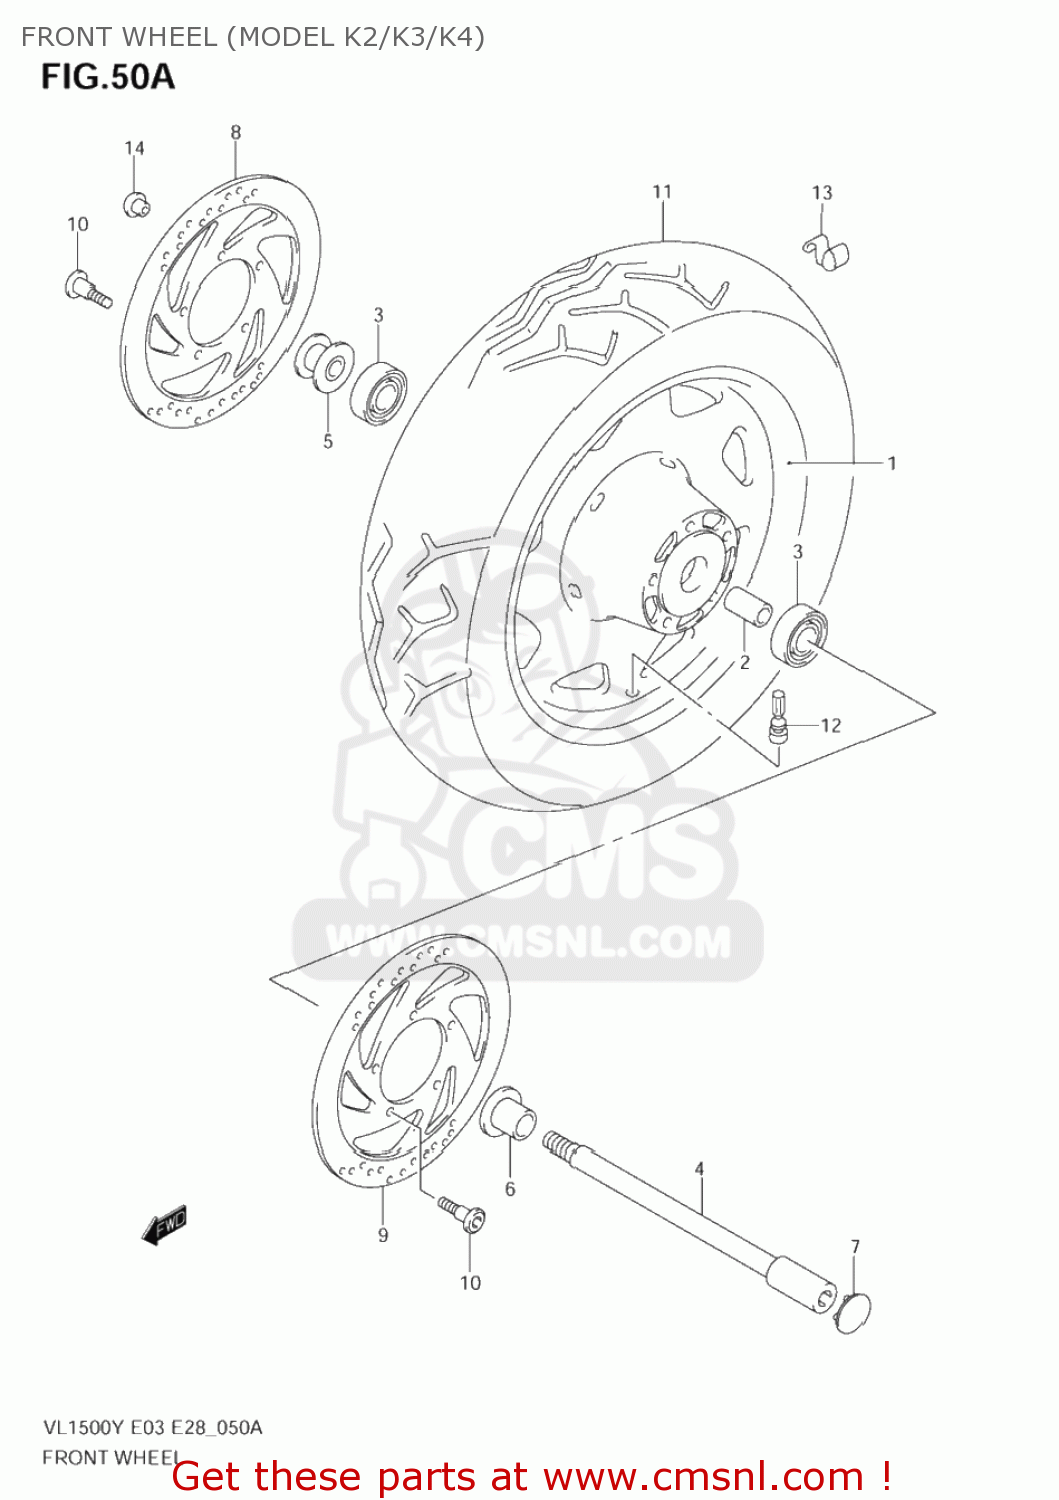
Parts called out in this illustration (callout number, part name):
1	WHEEL,FR(16XMT3.50)
2	SPACER,FR HUB BEARING
3	BEARING
4	AXLE,FR
5	SPACER,FR AXLE,R
6	SPACER,FR AXLE,R
7	CAP,FR AXLE
8	DISC,FR BRAKE,R
9	DISC,FR BRAKE,L
10	BOLT(8X33)
11	TIRE,FRONT 150/80-16.7
12	VALVE ASSY,WHEEL RIM(TR412)
13	WEIGHT,BAL. 30
14	CAP,FR AXLE
